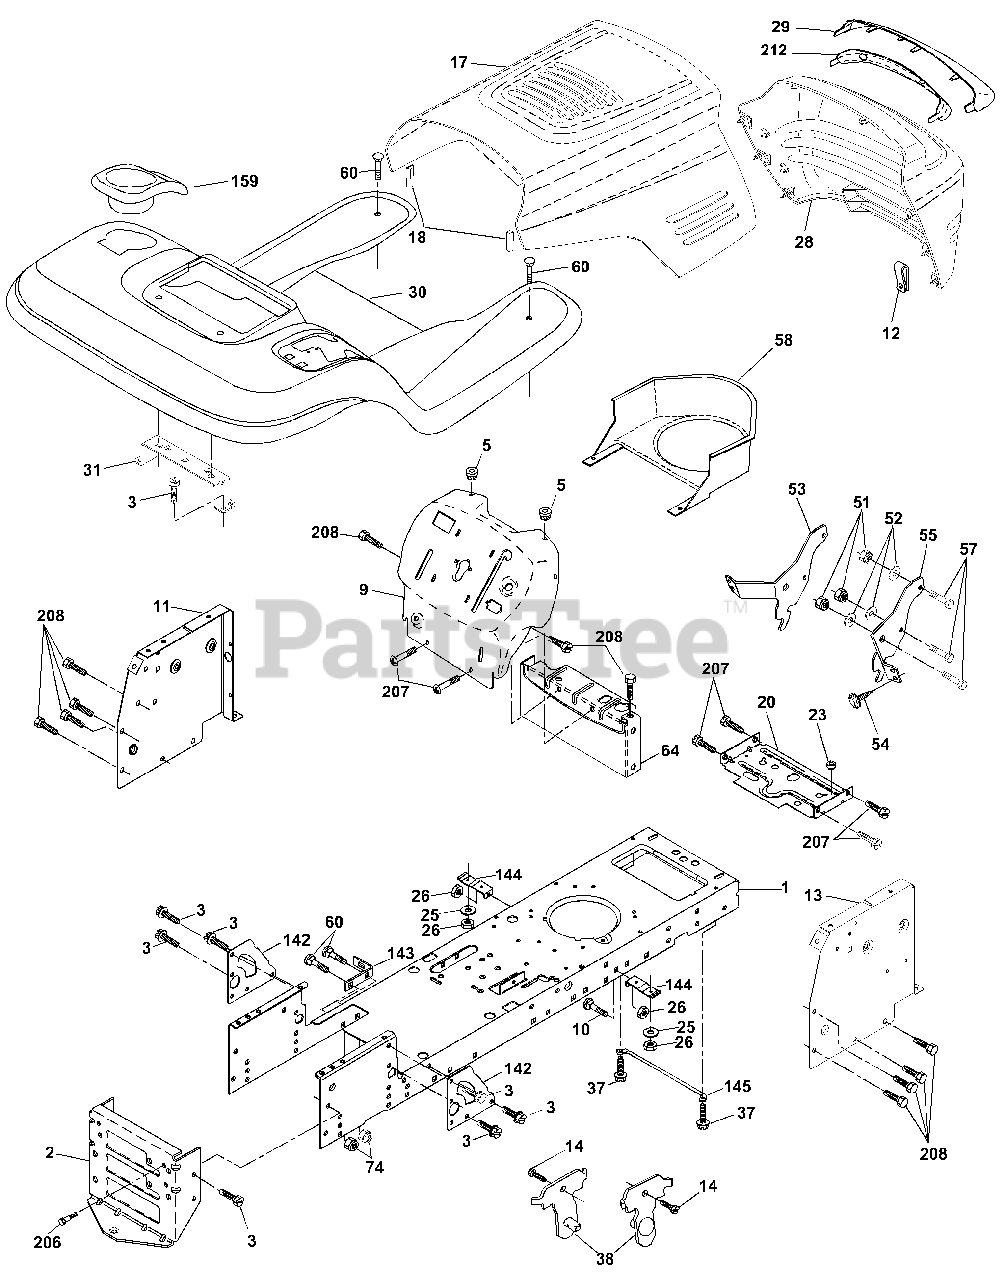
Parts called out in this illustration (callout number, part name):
1	Chassis Stamping
3	Screw 3/8-16x3/4
9	Dashboard
10	Bolt Rdhd Sqnk 3/8-16 Unc x 1
11	Panel Dash Lh
12	Clip Tinnerman Grille
13	Panel Dash Rh
14	Screw Thdrol 3/8-16 x 1/2
17	Hood
20	Plate Mtg Battery/Fuel Tank
25	Washer 13/32 x 13/16 x 12 Ga.
26	Nut Lock w/Insert 3/8-16 UNC
28	Grille Lens Asm
29	Lens
30	Fender
37	Screw Thdrol 5/16-18 x 1/2
38	Bracket Asm Pivot Mower Rear
51	Nut Lock w/Insert 1/4-20
52	Washer 9/32 x 7/8 x 16 Ga.
53	Bracket Grille Lh
54	Screw Hex Wshd 8-18 x 7/8
55	Bracket Grille Rh
57	Bolt Fin Hex 1/4-20 Unc x 3/4
58	Duct Air
60	Bolt RDHD SQNK 3/8-16 x 3/4
64	Dash Lower Stlt
74	Nut Crownlock 3/8-16
142	Plate Reinforcement Stlt
143	Bracket Swaybar Chassis
144	Bracket Ft Rest
145	Rod Pivot Chassis Hood
159	Cupholder YTGT Grey
206	Bolt Shoulder 5/16-18 TT
207	Screw Thdrol 5/16-18 x 1/2 TYTT
208	Screw Thdrol 3/8-16 x 1/2 Ty-TT
212	Insert Lens Reflect
